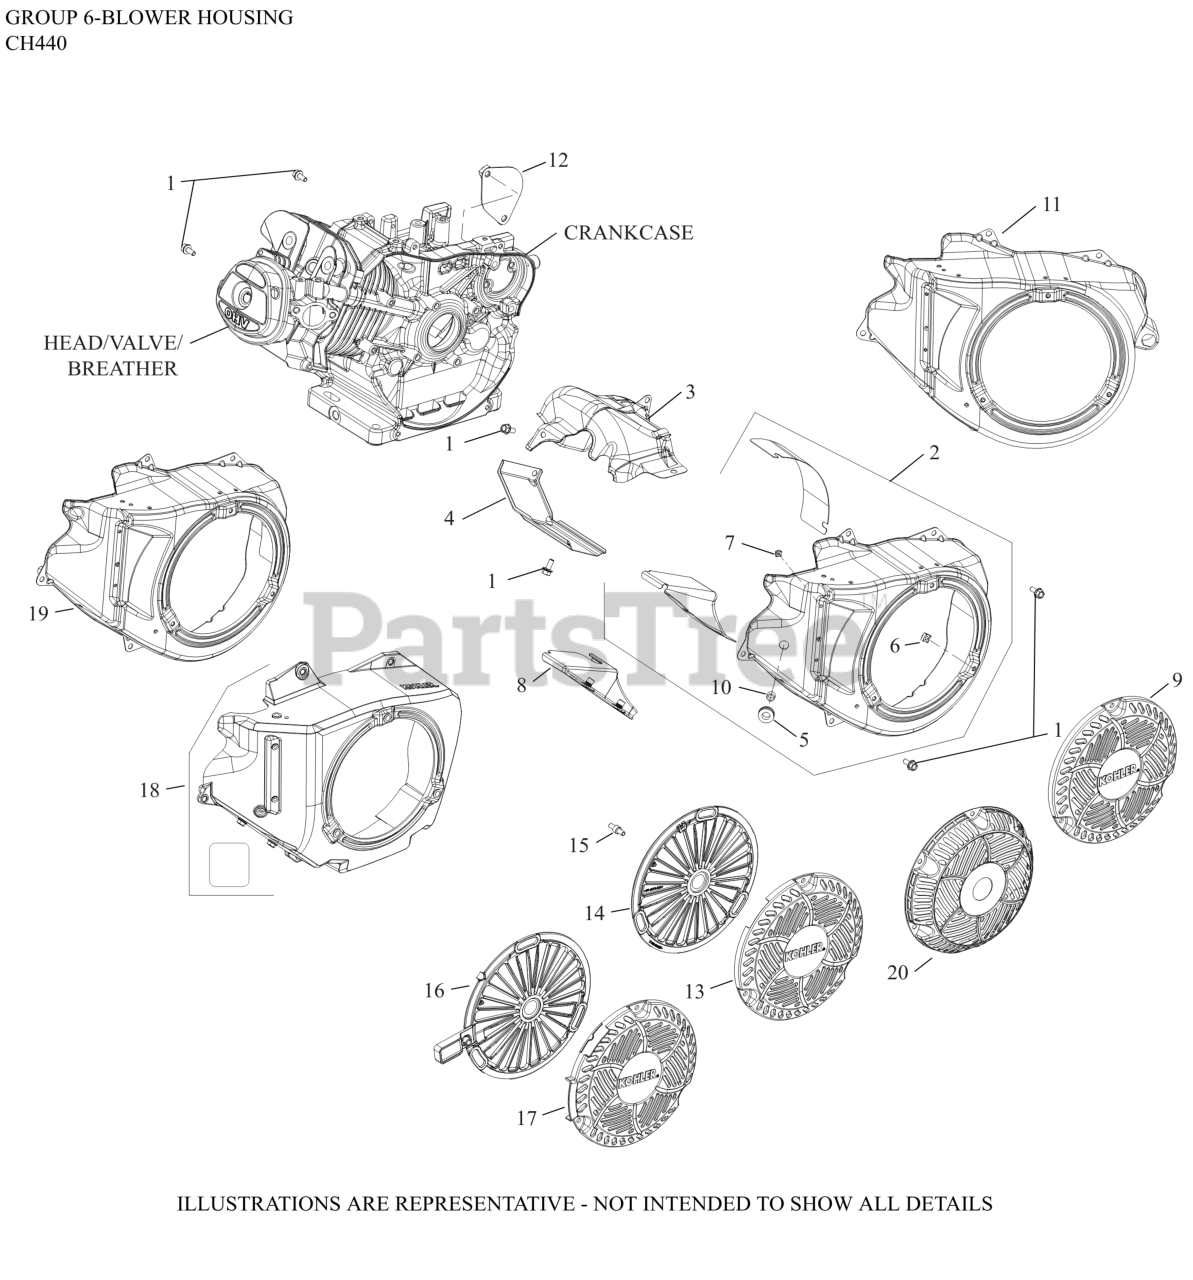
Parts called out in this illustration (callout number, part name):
1	SCREW, HEX FLANGE (M6)-USE 25 086 433-S
2	HOUSING, BLOWER ASSEMBLY
3	SHIELD, UPPER HEAT
4	SHIELD, CYLINDER HEAD
5	ISOLATOR, VIBRATION
6	NUT, BLOWER HOUSING (CKY)-(#DSC)
7	NUT, BLOWER HOUSING (CKY)-(#DSC)
